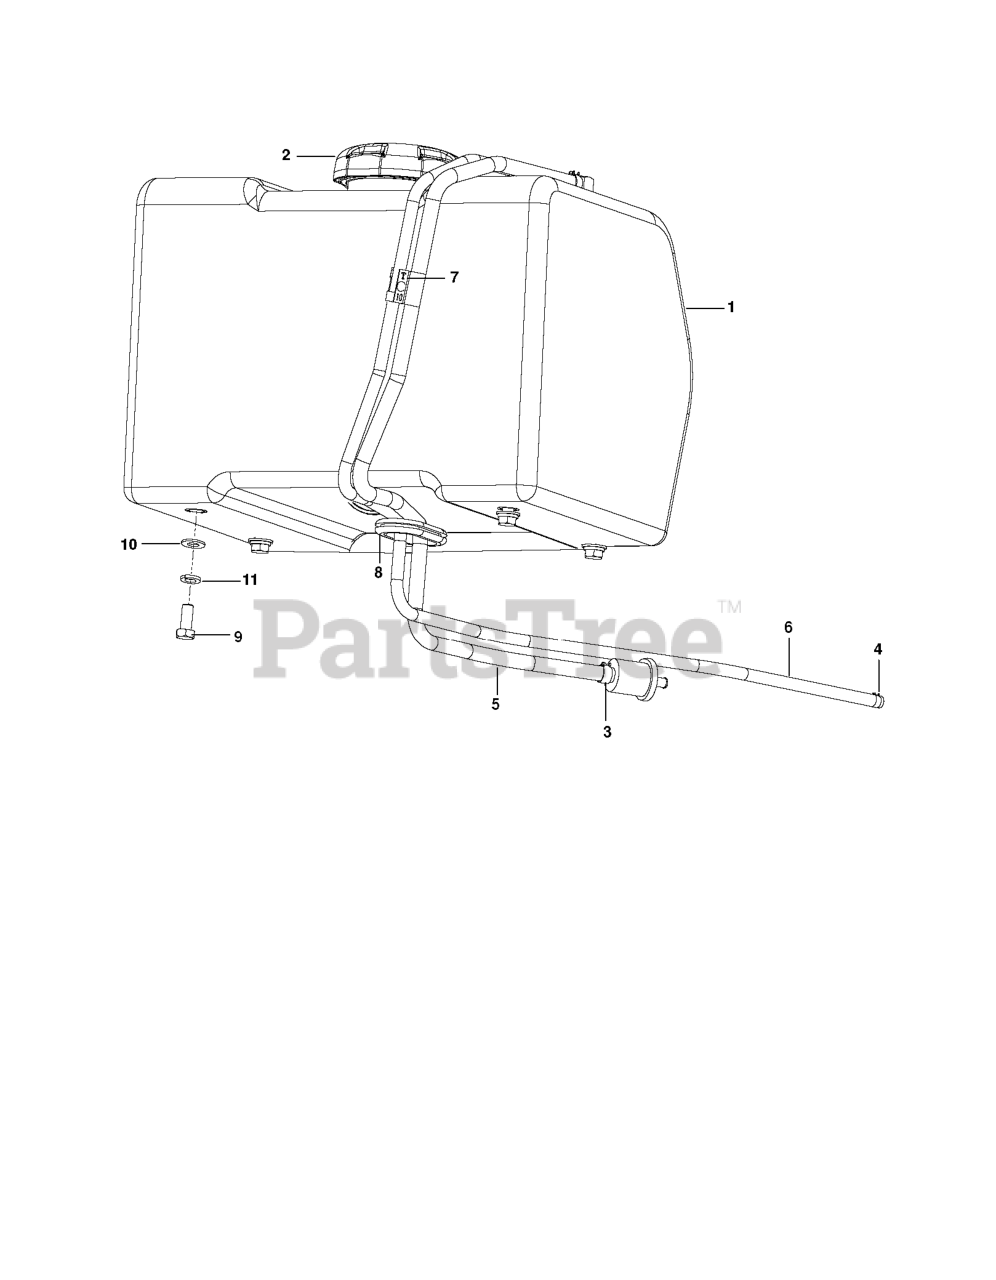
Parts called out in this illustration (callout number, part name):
1	TANK TANK, FUEL LOW PERM HUSQ
2	CAP CAP, FUEL NONVENT, AUTOLOC
3	CLAMP CLAMP, FUEL LINE
4	CLAMP CLAMP-HOSE, SPRING .188
5	HOSE HOSE, FUEL 1/4" X 32.75"
6	HOSE HOSE, VAPOR 3/16" X 56.00
7	CLIP CLIP, T, .38-.50
8	GROMMET GROMMET, 2.00"
9	BOLT BOLT HEX .38-16 X .75 GR5
11	WASHER WASHER, LK .38 X .094 R
